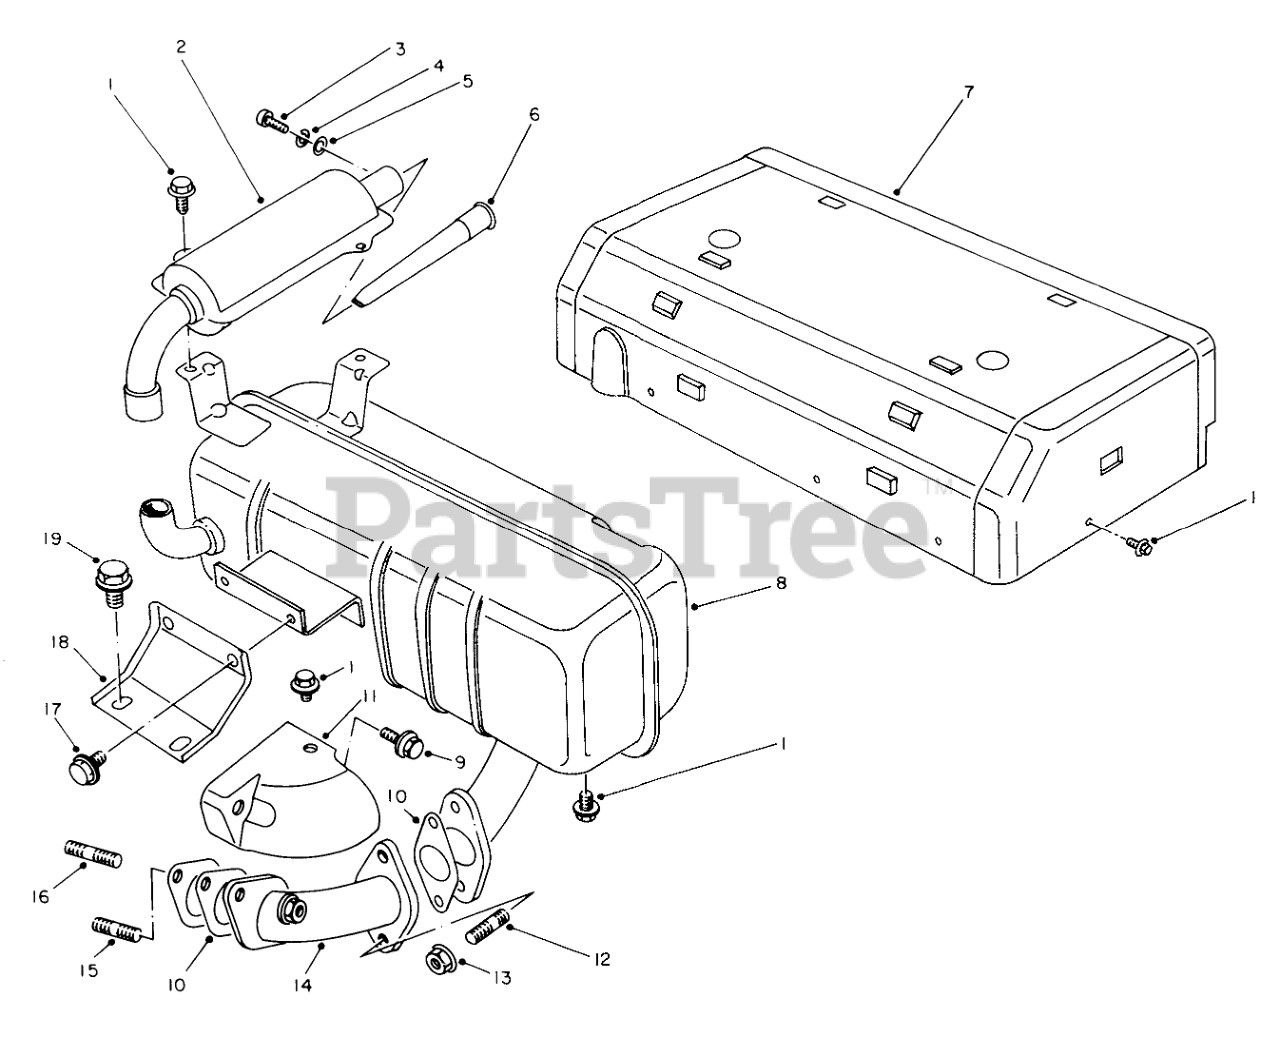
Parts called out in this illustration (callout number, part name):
2	Muffler
4	Lockwasher
5	Washer
6	Screw-Spark Arrester
7	Cover-Muffler
8	Muffler
10	EXHAUST GASKET
11	Cover-Exhaust Pipe
12	Stud Bolt
14	Exhaust Pipe
15	Stud Bolt
16	Stud Bolt
18	Brace
19	Bolt
